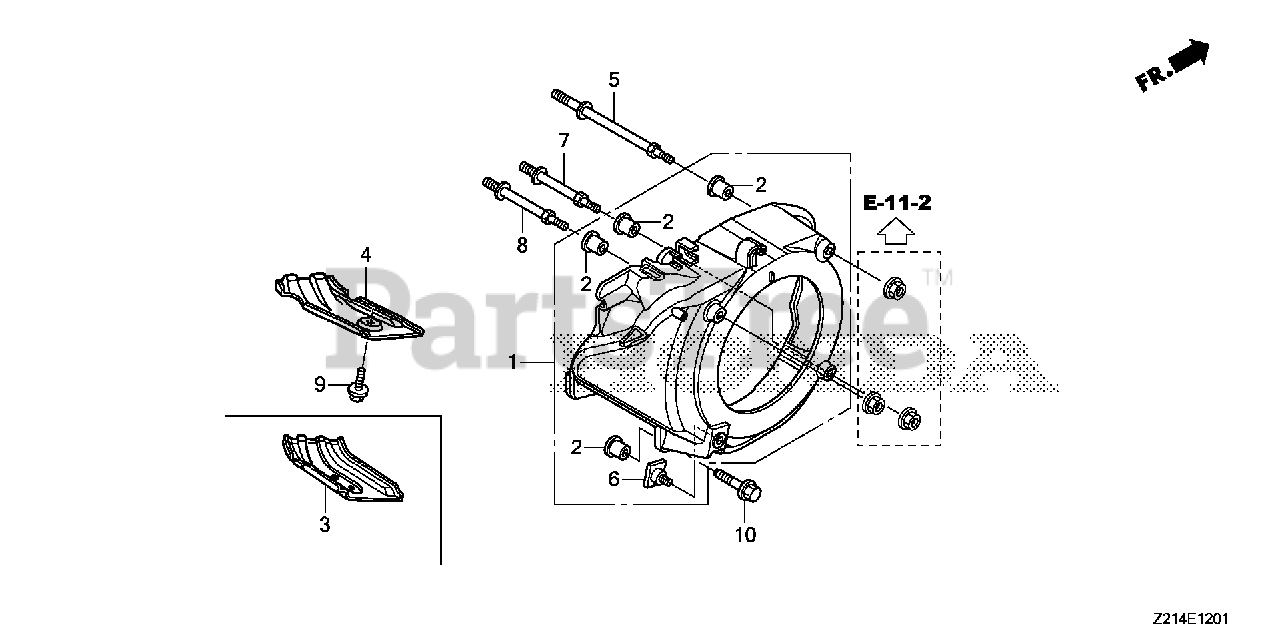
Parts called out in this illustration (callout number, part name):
1	COVER, FAN *NH1* (BLACK)
2	COLLAR, FAN COVER (Honda Code 5580527). (N/A: SEE ASSEMBLY)
5	BOLT, STUD (SEL)
6	BOLT, SPECIAL (6MM)
7	BOLT, STUD
8	BOLT B, STUD
9	BOLT, FLANGE (6X12) (CT200)
10	BOLT, FLANGE (6X25) Use up to Engine SN 2056819.
